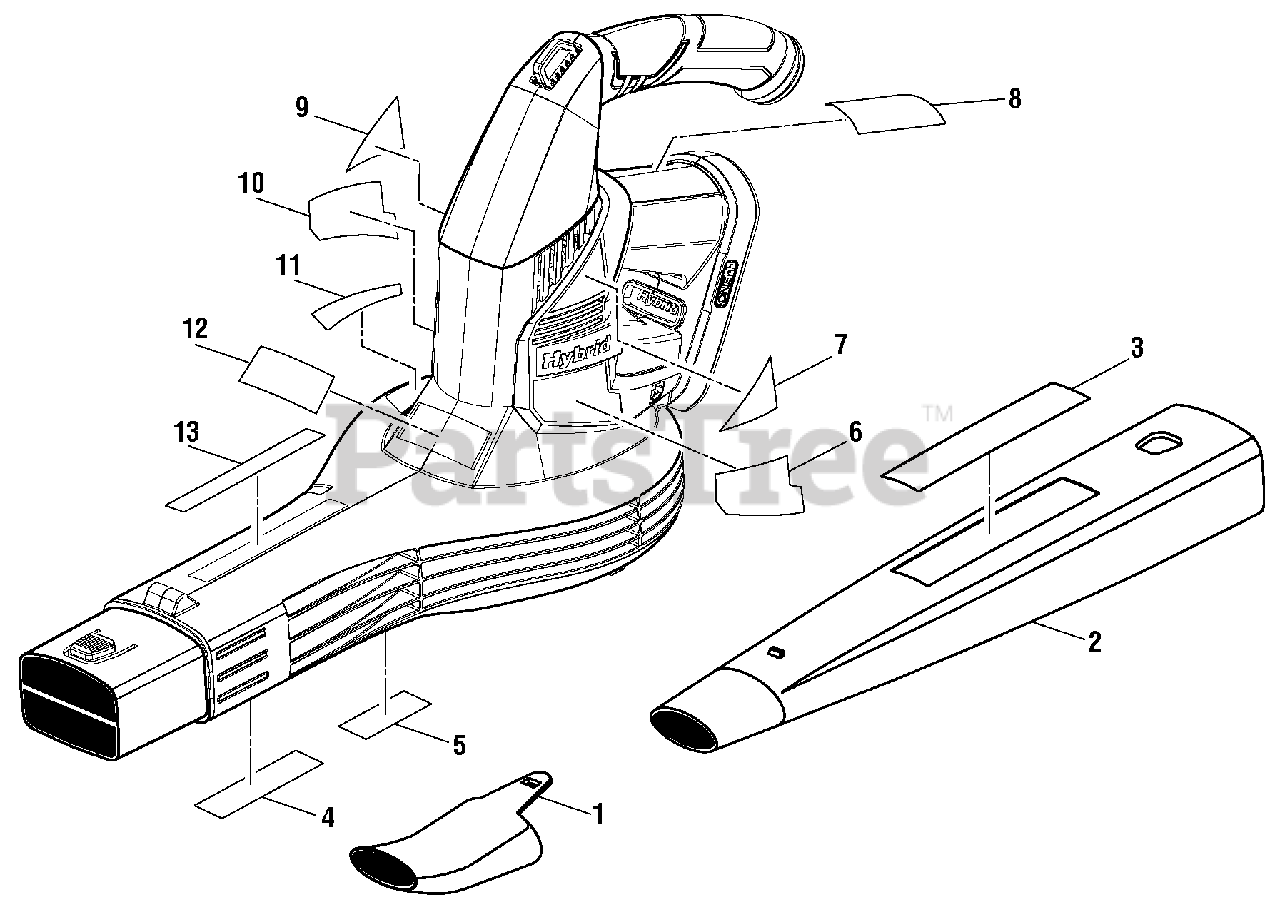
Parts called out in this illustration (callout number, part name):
1	High Velocity Nozzle
2	Blower Tube
3	Blower Tube Logo Label
4	Warning Label (French/Spanish)
5	Data Label
6	Left Bottom Label
7	Left Top Label
8	Hybrid Icon Label
9	Right Top Label
10	Right Bottom Label
11	Warning Label (English)
12	Logo Label
13	Warning Icon Label
